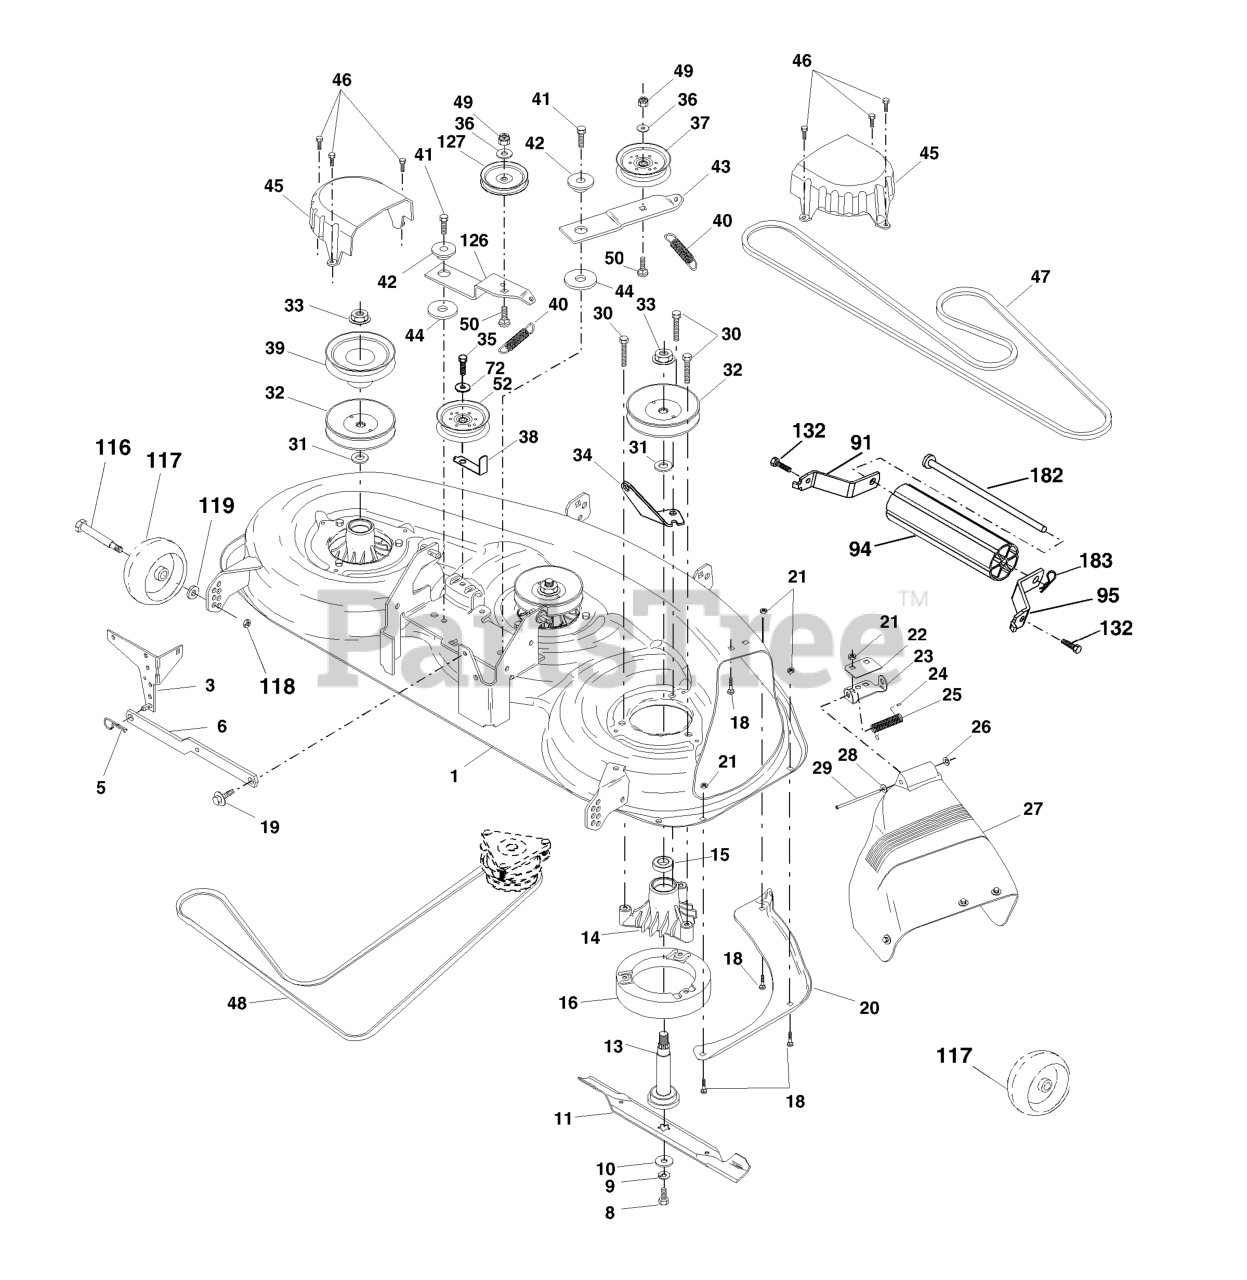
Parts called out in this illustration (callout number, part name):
1	DECK.SVC.46"156948X418
3	BRACKET SWAY BAR
5	RETAINER-SPRNG RB
6	BAR SWAY DECK
8	BLADE BOLT
9	LOCKWASHER
10	WASHER.BLADE
11	BLADE.46".HI-LIFT.PREMIUM
11	MULCH BLADE 46"
13	SHAFT.ASM.W/BEARING
14	HOUSING.MANDREL.44/46" VENT
16	STRIPPER.MANDREL.ROUND.BLACK
18	BOLT
19	BOLT SHD 5/16-18
20	BAFFLE, VORTEX MOWER 46"
21	LOCKNUT
22	STIFFENER BRACKET
23	DEFLECTOR BRACKET
24	CAP-SLEEVE LT
25	TORSION SPRING
26	NUT PUSH M
27	DEFLECTOR
28	Washer 11/32 x 5/8 x 16 Ga.
29	ROD.HINGE
30	SCREW, WASHER HEAD
31	WASHER
32	MANDREL PULLEY
33	NUT, FLG TOPLOCK 9/16"
34	ANCHOR, SPRING DECK 46"
35	SCREW LT
36	WASHER
37	PULLEY.IDLER.FLAT
38	REPL BY 532 1560-86
39	REPL BY 532 1449-17
40	SPRING.SEC.44"VEN
41	SCREW.3/8-16
42	SPACER RETAINER
43	ARM IDLER DECK 46"
44	HARDENED WASHER
45	COVER MANDREL 46
46	SCREW.1/4-20X5/8
47	BELT V SECONDARY
48	V-BELT PRIMARY 50"
50	BOLT.3/8-16X1.50
52	PULLEY.IDLER.FLAT.46".PRIMARY
72	WASHER
91	BRACKET ASM NOSEROLLER LH
94	NOSE ROLLER
95	BRACKET ASM NOSEROLLER RH
116	BOLT, SHOULDER
117	WHEEL GAGE DONUT
118	LOCKNUT
119	WASHER.5/16.FLAT.STE.STD.
126	ARM IDLER PRIM 46
127	REPL BY 532 1467-63
132	SCREW 3/8-16X3/4
182	ROD ROLLER NOSE STANDARD
183	SPRING RETAINER
